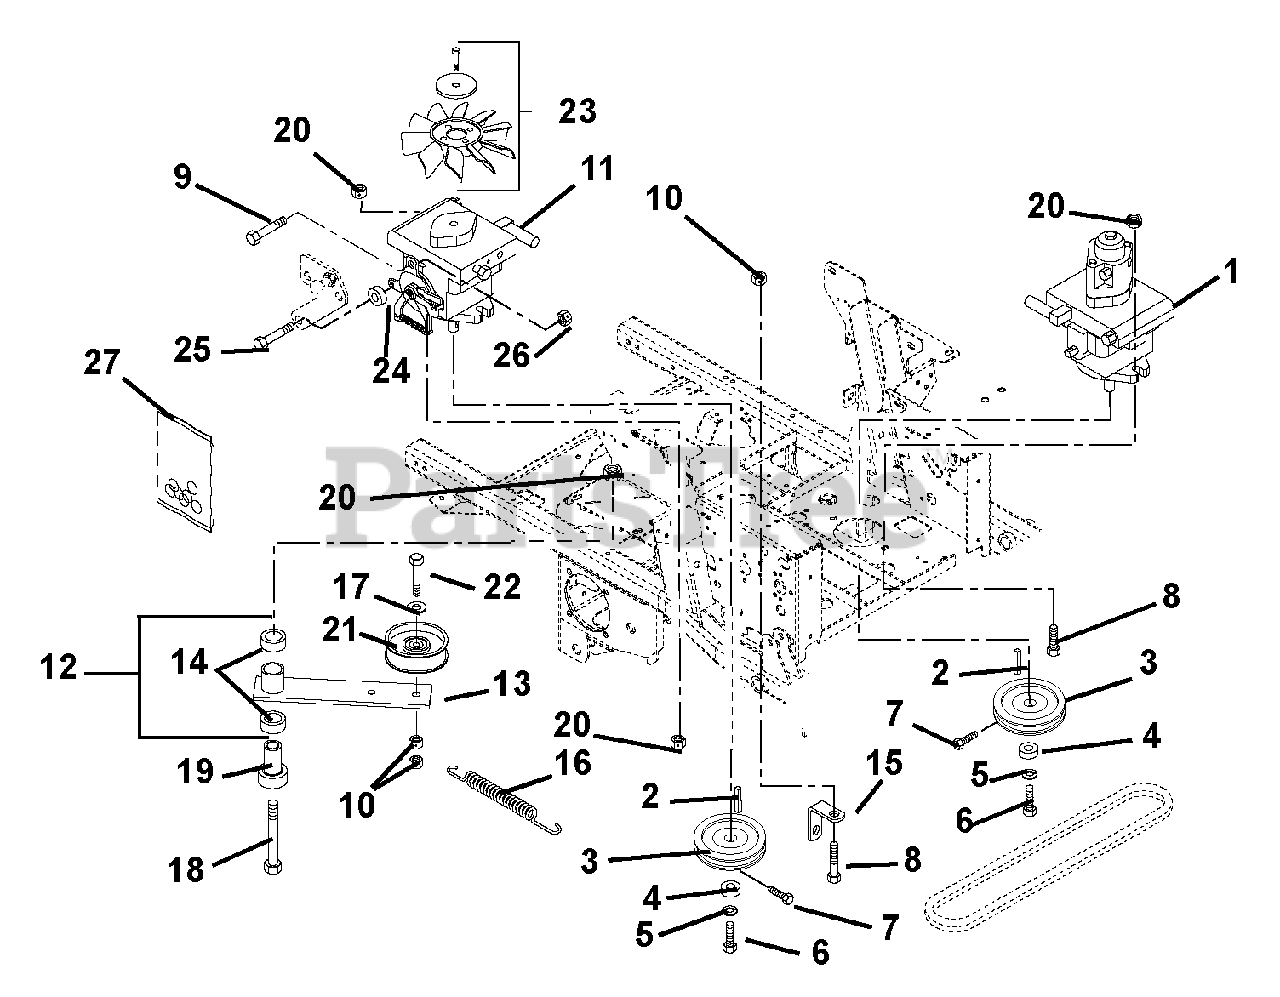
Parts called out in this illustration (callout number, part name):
1	Pump, Hydraulic with Auxiliary
1	Pump, Hydraulic
2	Key, Square 5 x 5 x 30mm Plain
3	Sheave, Poly V .671 x 4.125
4	Washer, Flat Steel .281 x 1.000 x .063
5	Washer, Locking .25 x .062
6	Bolt, Hex M6 x 1.0 x 16
7	Screw, Socket Head .25-20 x .50
8	Bolt, Hex .50-13 x 1.50 Grade 5
9	Bolt, Hex .31-18 x .75 Grade 5
10	Nut-Locking-Top-Flange .38-16
11	Pump, Hydraulic BDP-21 with Thru Fan
12	Assembly, Idler Arm Guard Drive
13	Weldment, Idler Arm Ground Drive
14	Bearing, 1.00 x 1.12 x .75
15	Anchor, Spring Idler
16	Spring, Tension .120 x .845 x 6.500
17	Washer, Flat Steel .39 x .75 x.125
18	Bolt, Hex .50-13 x 3.50 Grade 5
19	Bearing, Pedestal
20	Nut, Locking Top Flange .50-13
21	Idler, Flat 4.00 x 0.38
22	Bolt, Hex .38-16 x 2.25 Grade 5
23	Fan, Hydro Pump Cooling
24	Spacer .318 x .43 x .375
25	Bolt, Hex .31-18 x 1.25 Grade 5
26	Nut, Locking Top Flange .31-18
27	Kit, Pump Seal
